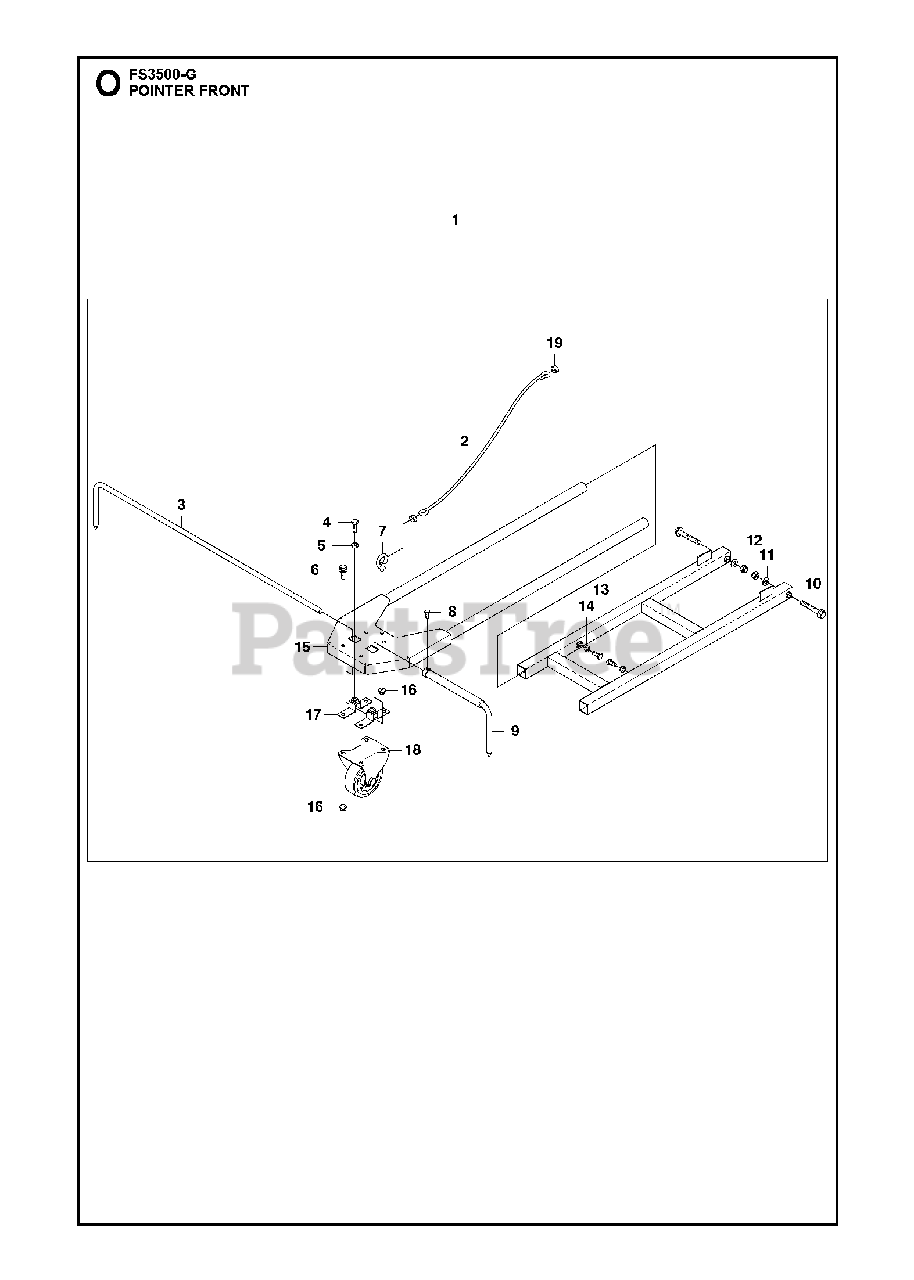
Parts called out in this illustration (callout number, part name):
5	HEXAGON NUT
8	SCREW EHHM
11	WASHER
12	HEXAGON LOCKING NUT
14	HEXAGON NUT
16	HEXAGON NUT FLANGE
